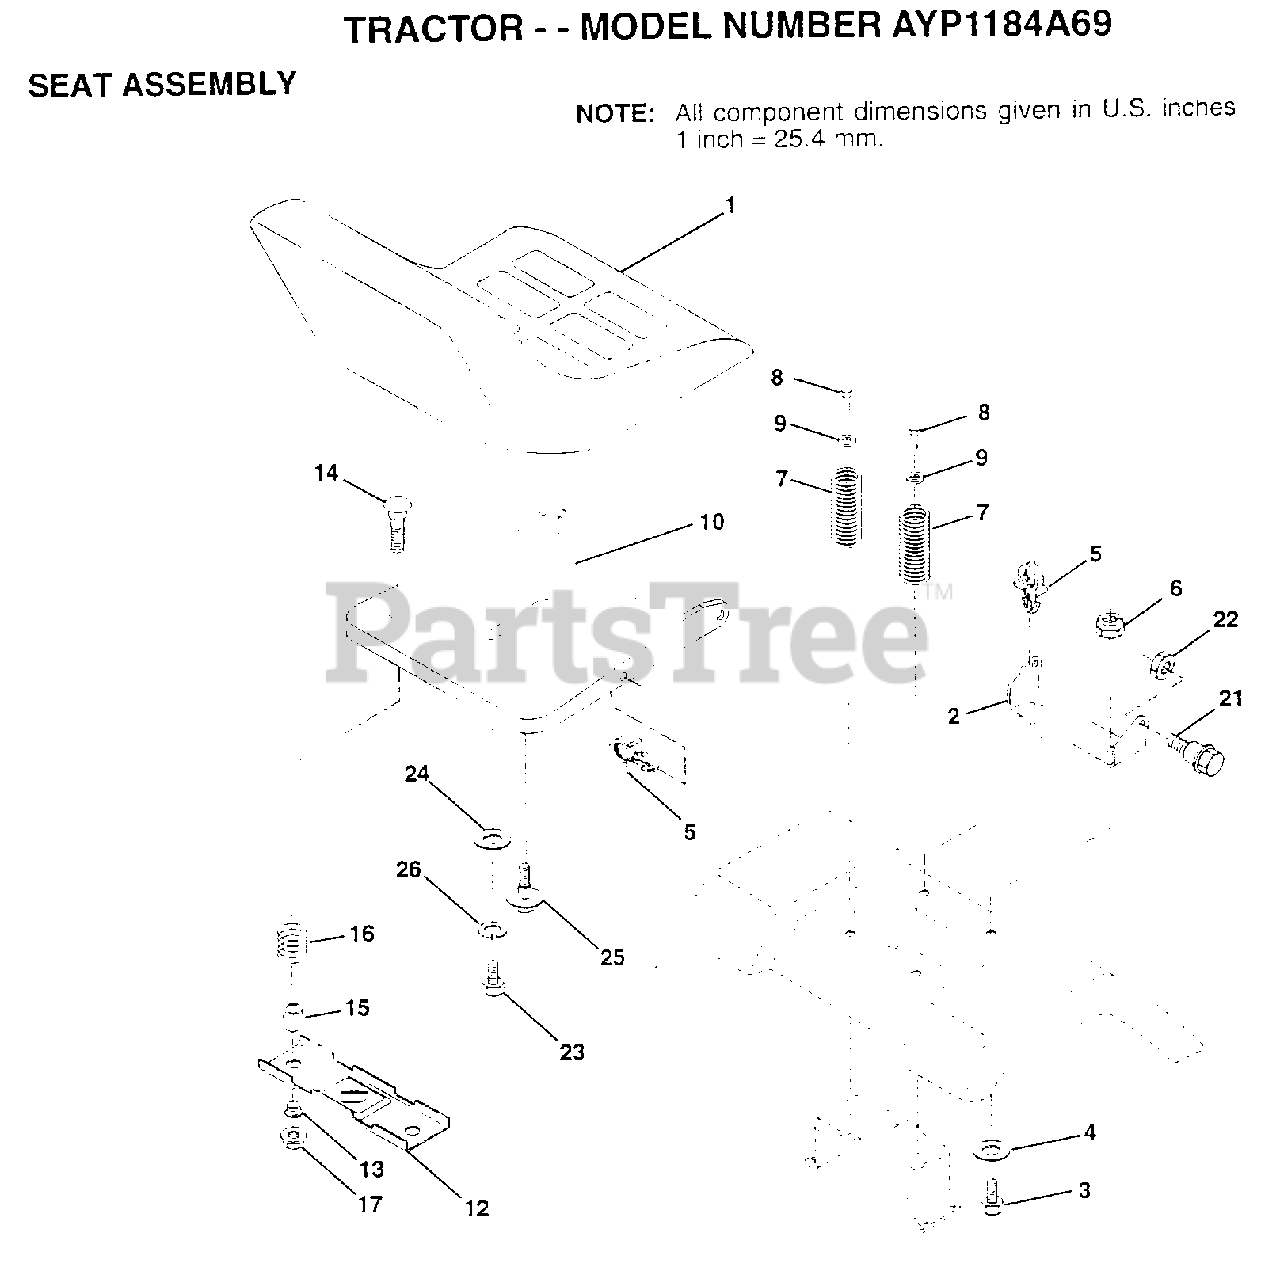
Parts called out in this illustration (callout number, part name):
2	BRACKET PVT SEAT
3	BOLT
4	WASHER PM
5	CLIP.PUSH-IN.HING
6	NUT
7	SPRING COMPRESSIO
8	SCREW GTV
9	WASHER
12	BRKT SWITCH
13	BUSHING
15	SPLIT SPACER
16	SPRING
21	BOLT.SHLD.5/16-18
22	NUT
23	BOLT
24	WASHER
25	"BOLT,SHOULDER"
26	LOCKWASHER
